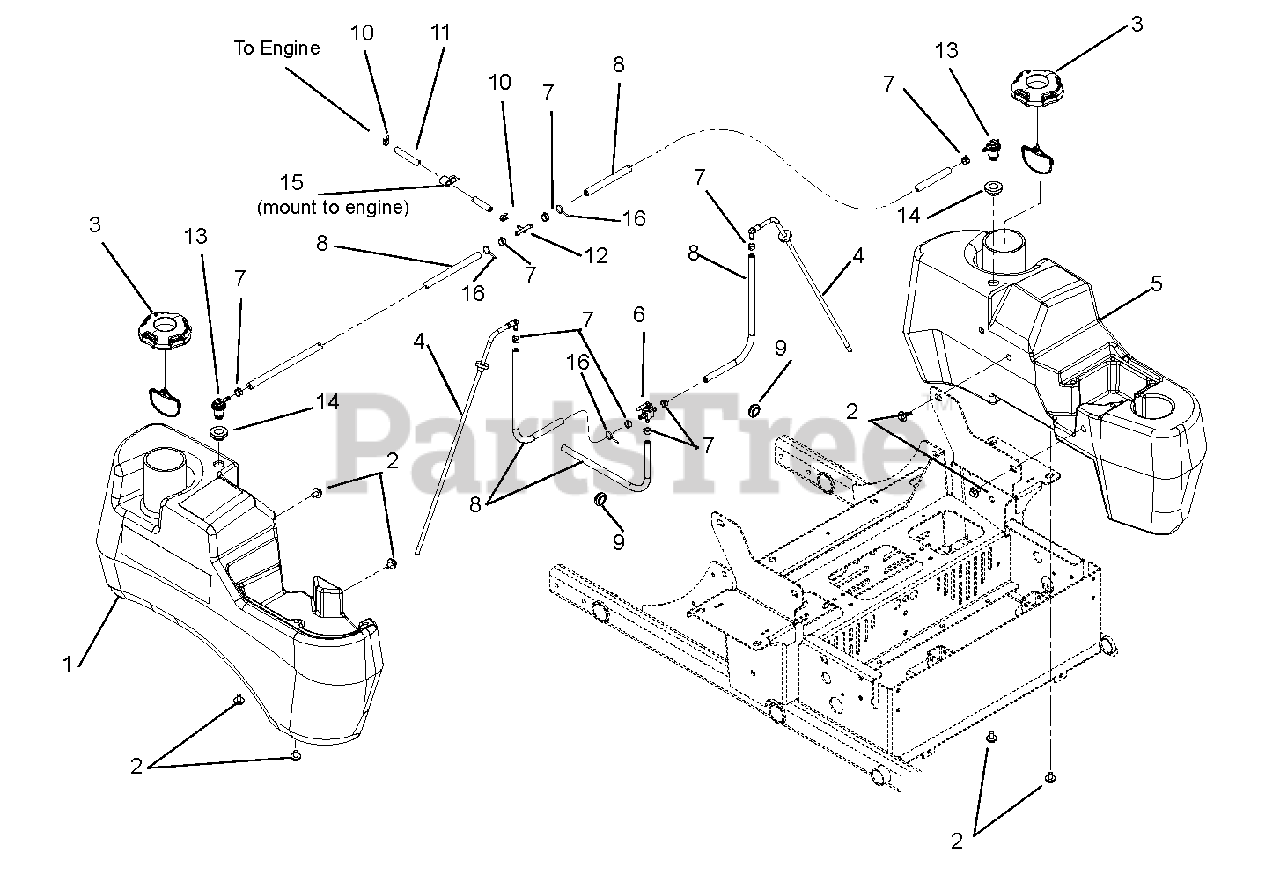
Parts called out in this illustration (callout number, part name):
1	Tank, Right Hand Fuel
2	Bolt, SEMS .31-18 x .62
3	Cap, Fuel, EPA
4	Assembly, Large Tank Fuel Pick-Up
5	Tank, Left Hand Fuel
6	Valve, Fuel
7	Clamp, Fuel Line
8	Hose, .25 Low-Perm Bulk Gas
9	Grommet, Rubber 5/8 ID/1.13 OD
10	Clamp, Hose, Spring .188
11	Hose, .188 Low-PERM Bulk Gas
12	Tee, 1/4HS Run x 3/16HS Branch
13	Valve, Combination
14	Grommet, Remote Vent Nitrile
16	Cable Tie with Tree (.25 hole)
